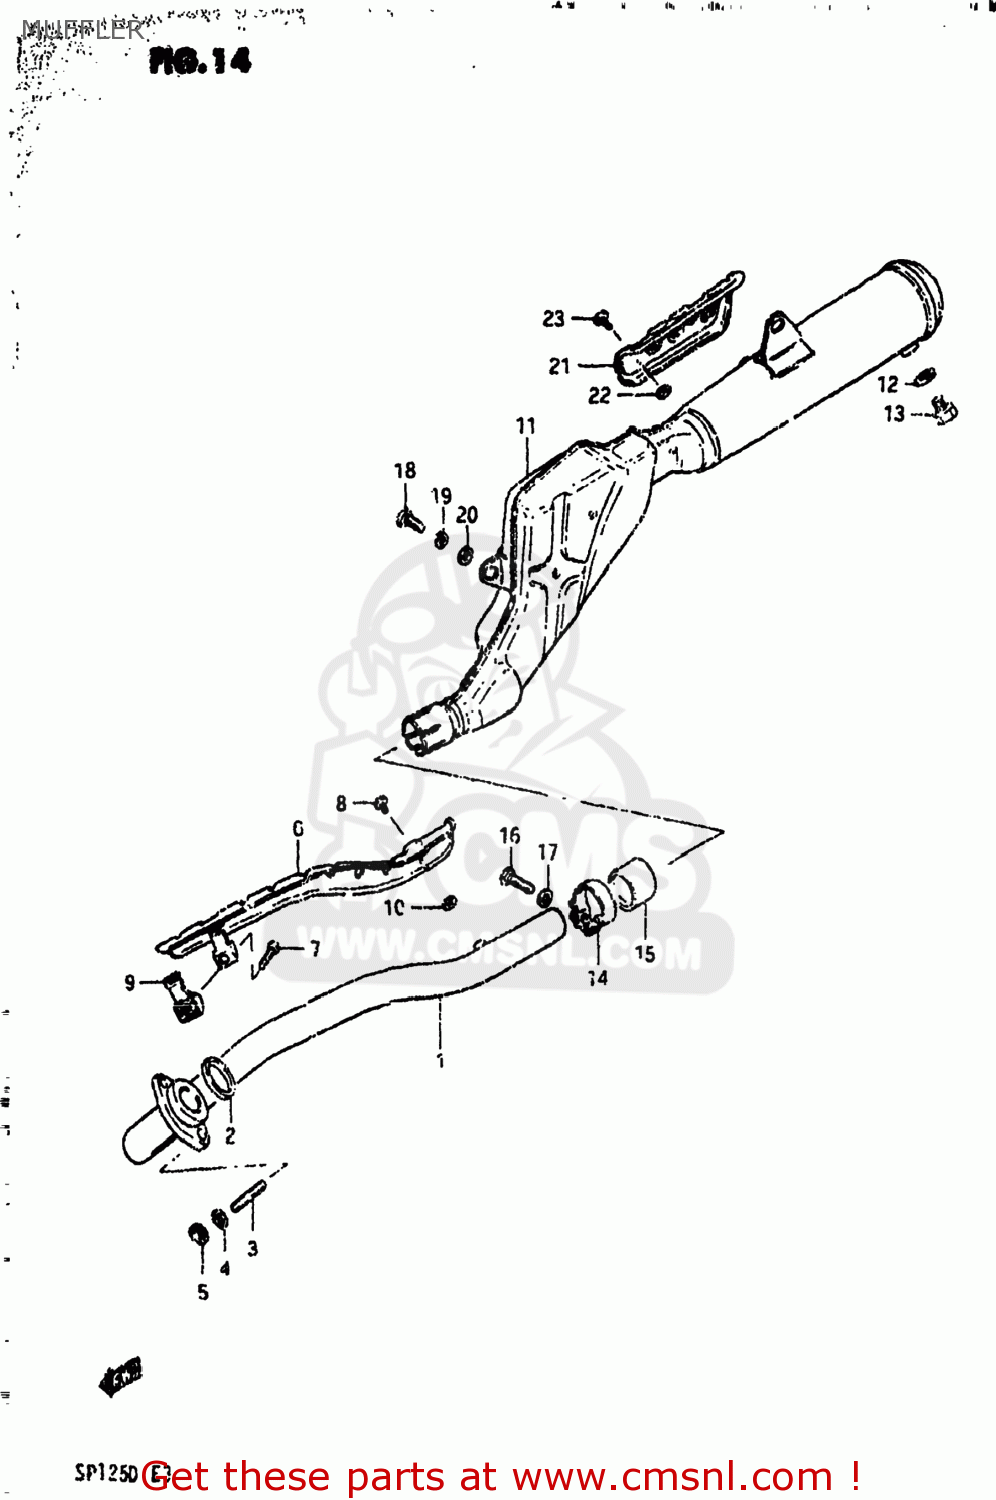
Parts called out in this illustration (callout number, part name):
1	PIPE,EXHAUST
2	GASKET,EXHAUST PIPE (NAS)
3	STUD BOLT L:20
4	LOCK WASHER
5	NUT
6	COVER,EXHAUST PIPE
7	SCREW 5X20
8	SCREW
9	CLAMP,EXHAUST PIPE COVER
10	GASKET 6.2X12X1.5 (MCA)
11	MUFFLER ASSEMBLY
12	GASKET(12.1X16.2X3.7) (NAS)
13	PLUG(12X9)
14	CLAMP,MUFFLER CONNECTOR
15	CONNECTOR,MUFFLER
16	BOLT 8X25
17	WASHER,8.5X16X
18	BOLT
19	LOCK WASHER
20	WASHER,8.5X16X
21	COVER,MUFFLER
22	GASKET 6.2X12X1.5 (MCA)
23	SCREW
